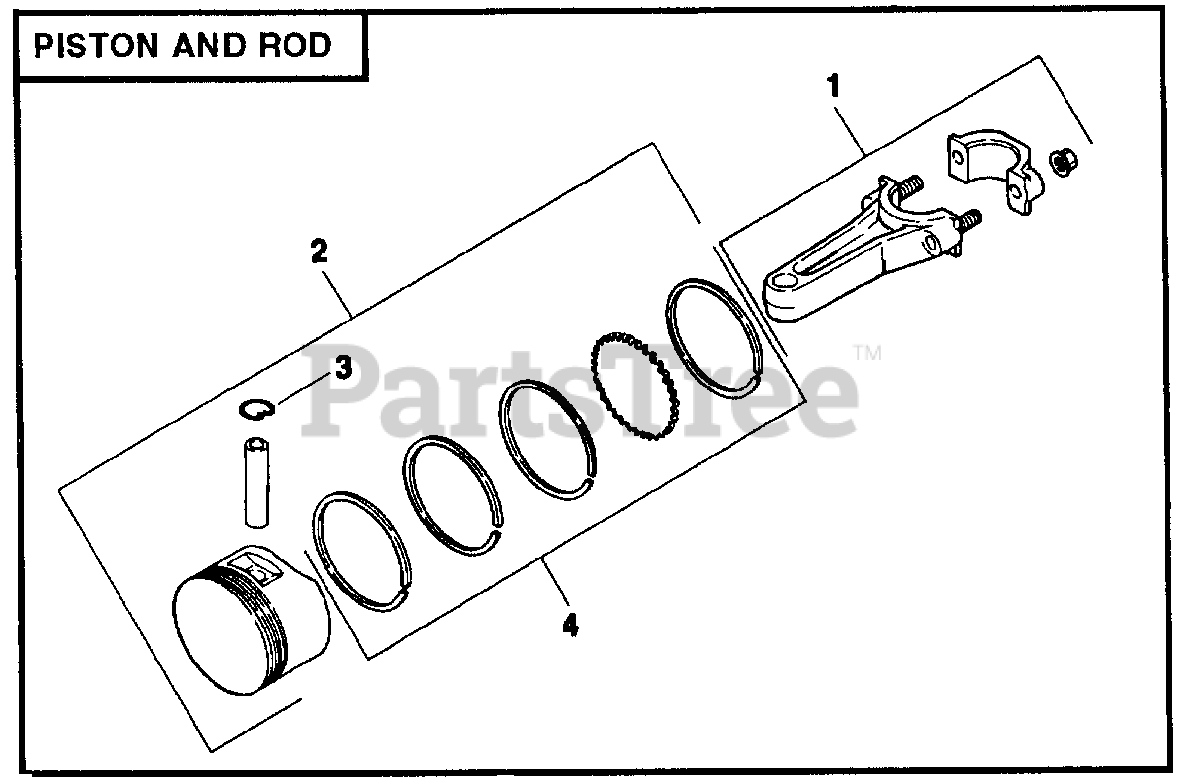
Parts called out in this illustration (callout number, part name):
1	CONNECTING ROD
1A	CONNECT. ROD .010"
2	PISTON W/RING SET
2A	PISTON W/RING SET .003"
2B	PISTON W/RING SET .010"
2C	PISTON W/RING SET .020"
2D	PISTON W/RING SET .030"
3	RETAINER, PISTON PIN
4	RING SET, .003"
4A	RING SET, .010"
4B	RING SET, 020"
4C	RING SET, .030"
